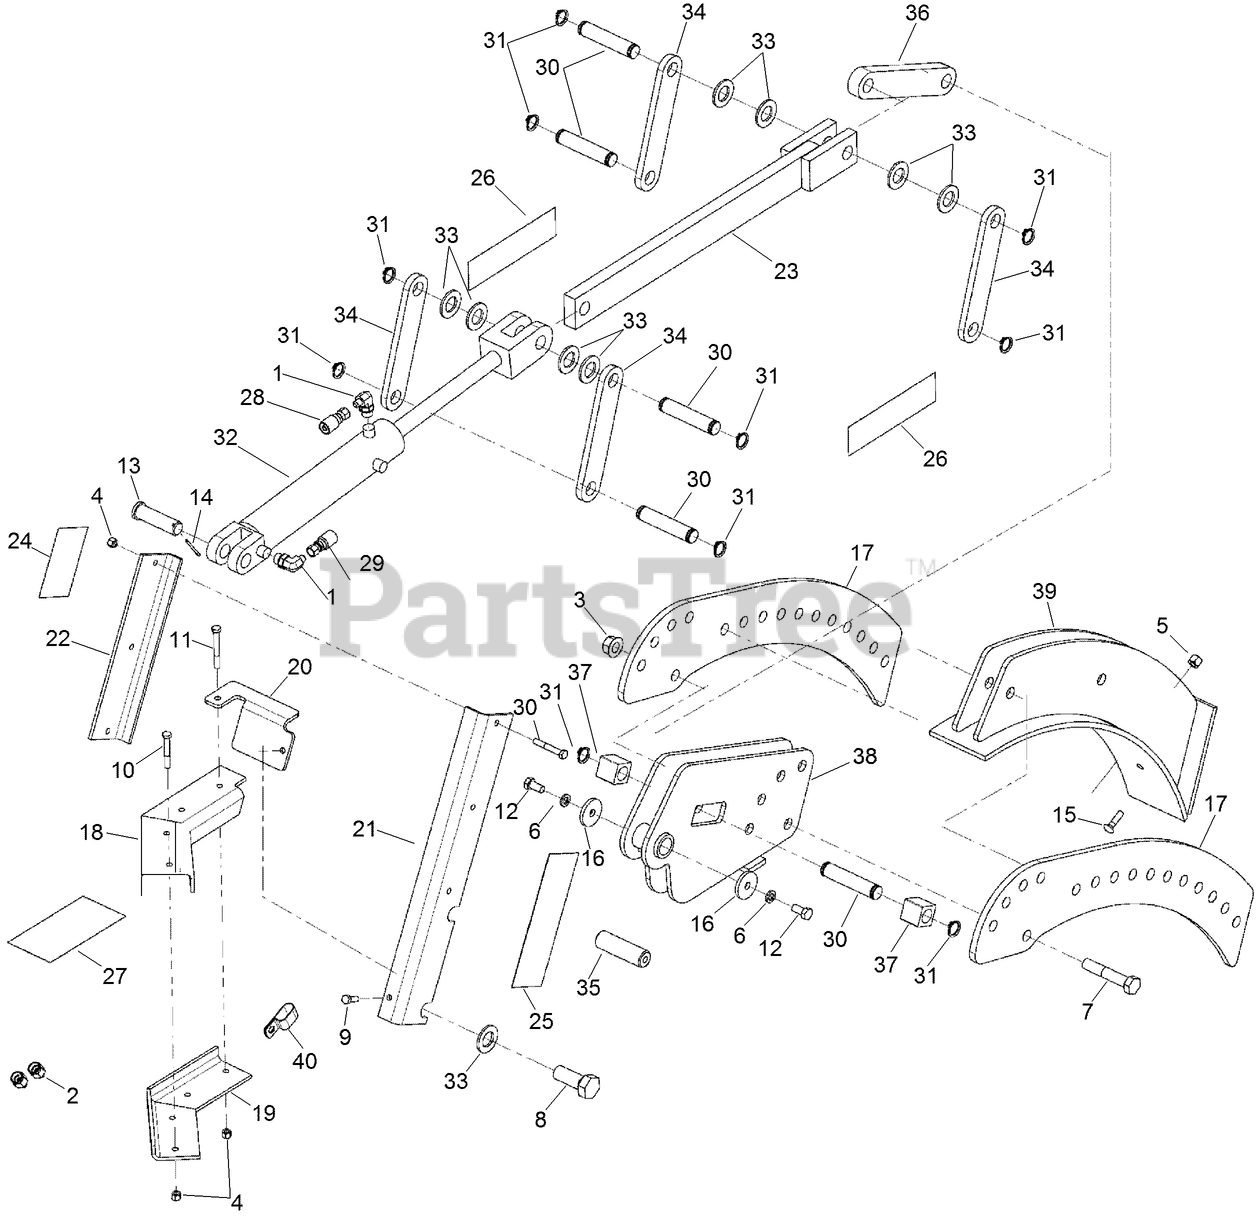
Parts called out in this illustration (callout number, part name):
1	ELBOW-90 Adj 37FL, 3/8 x 1/2 Tube
3	NUT-HEX FLANGE
4	NUT-HEX
5	NUT-HEX
6	WASHER - Spring Lock Reg .500 in PHC
9	SCREW-HH
10	SCREW-HH
11	BOLT-hex, 3/8 NC x 3 inch
12	SCREW-HH
13	PIN-clevis, 1 x 3-1/2 inch, hardened
14	PIN-cotter, 5/32 x 1-3/4 inch
15	BOLT - Round Hd .375 x 1.50 GR5 ZND
16	WASHER-FLAT
17	PLATE-CRUMBER CONNECTOR
18	ANGLE WELDMENT - Conduit, Upper
19	ANGLE WELDMENT - Conduit, Lower
20	ANGLE - Tie
21	ANGLE - Conduit (long)
22	ANGLE - Conduit (short)
23	BAR WELDMENT - Extension
24	DECAL-DANGER, ENTANGLE HAZZARD
25	DECAL-Danger, Trencher Entanglement Hazard
26	DECAL-Danger, Entanglement Hazard
27	DECAL - Hyd Crumber Oper Instructions
30	PIN-CYLINDER, ROD
31	RING - Snap
32	ASSEMBLY - Cylinder
34	LINK - Crumber, Straight
35	PIN-PIVOT, CRUMBER PIVOT
36	LINK-CRUMBER PUSH
37	BLOCK-SLIDE - SQ. BAR
38	PIVOT WELDMENT - Crumber
39	SHOE WELDMENT - Crumber
40	CLAMP-DOUBLE
